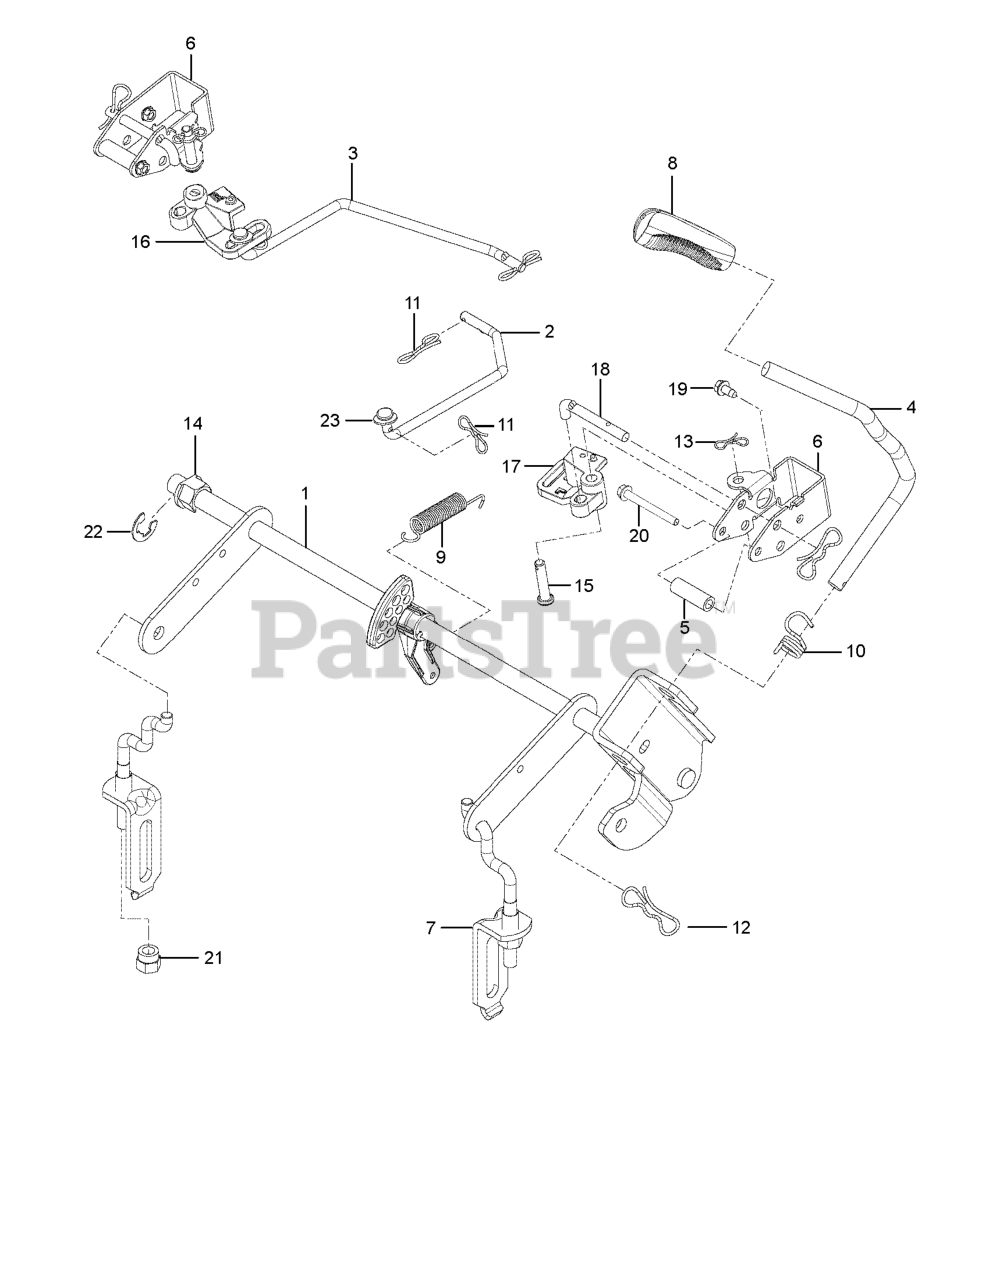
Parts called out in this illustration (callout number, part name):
1	SHAFT ASSY DECK LIFT WELDMENT
2	LINK.BRAKE.PARK.UPPER.LH
3	LINK.BRAKE.PARK.UPPER.RH
4	HANDLE LIFT ZTR
5	SPACER.334.ID.5.OD.1.5.L
6	BRACKET.BELLCRANK.PBRAKE X431
7	LINK.ASM.RZ.LIFT.SERVICE
8	GRIP.HANDLE.LIFT.PVC.BLACK
9	RETURN.BRAKE.PARK.AUTO
10	SPRING.TORSION.LIFT.HANDLE
11	PIN COTTER;LOCKING;BOWTIE;1IN
12	PIN.COTTER.7/16.BOW TI.
13	PIN.COTTER.5/16.BOW TI
14	PLASTIC NUT
15	PIN.5.16X1.5
16	BELLCRANK.RH
17	BELLCRANK.LH
18	ROD.PUSH.BRAKE
19	SCREW.1/4-20X5/8
20	SCREW THD;ROLL;1/4-20 X 2.25
21	NUT, LIFT LINK 7/16-20
22	RETAINING RING LT
23	WASHER
